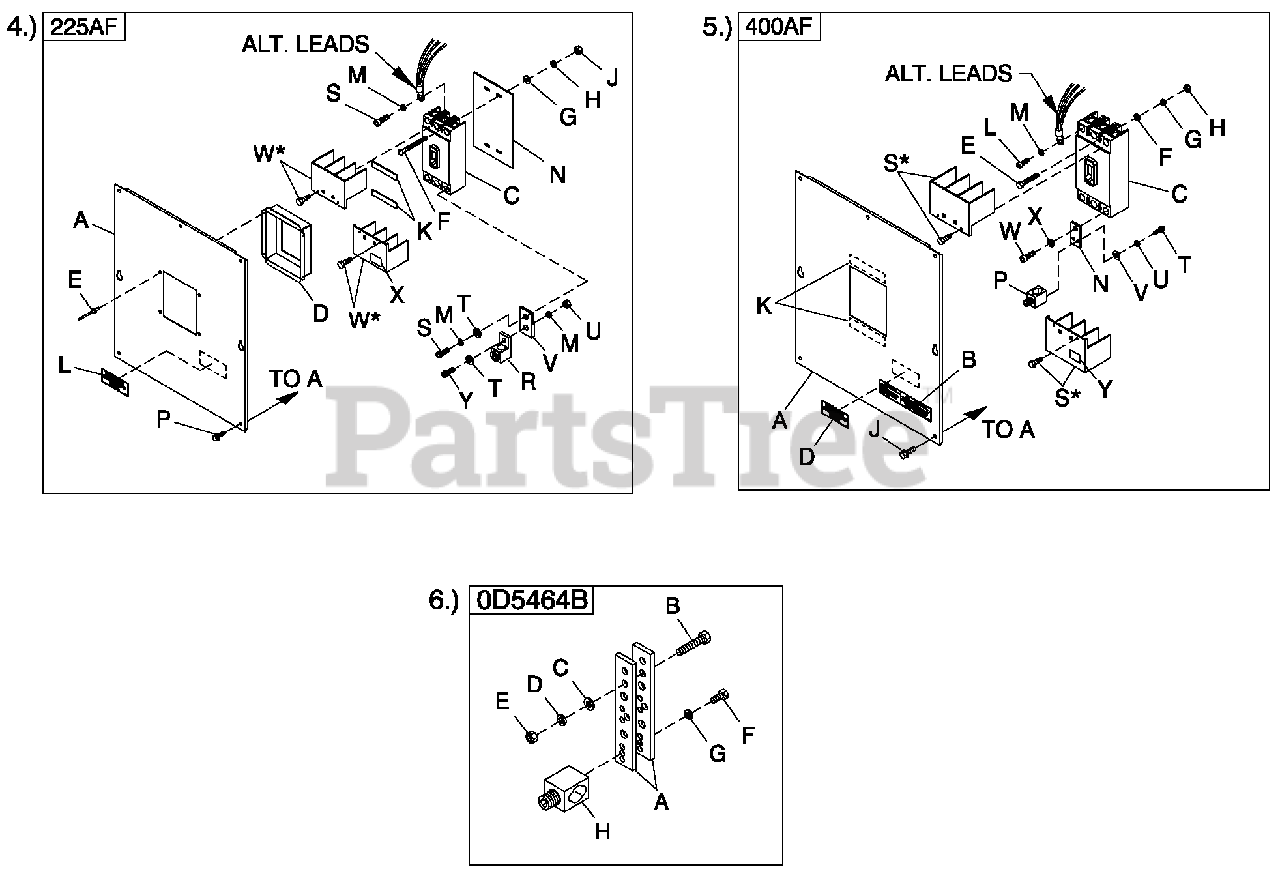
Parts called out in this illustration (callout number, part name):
A	COVER CB C3 225AF
C	CIRCUIT BREAKERS 200A FRAME
D	COVER CB DISH 225AF
E	RIVET POP .125 X .275 SS
F	SCREW RHM #8-32X3-1/4
G	WASHER FLAT #8 ZINC
H	WASHER LOCK #8-M4
J	NUT HEX #8-32 STEEL
K	TAPE ELEC 1/2 FOAM
L	DECAL CUSTOMER CONNECT INSIDE
M	WASHER LOCK M8-5/16
N	INSULATOR CB 225AF
P	SCREW THF M6-1 X 16 N WA Z/JS
R	LUG SLDLSS 300 MCM-6 AL/CU
S	SCREW SHCM8-1.25X 20 G8
T	WASHER FLAT 5/16-M8 ZINC
U	NUT HEX M8-1.25 G8 CLEAR ZINC
V	BUS BAR 200A LUG ADAPTOR
W	TERMINAL COVER CB
X	DECAL TERMINAL SHOCK HZD BI
Y	SCREW SHC M8-1.25 X 25 G12.9
A	COVER CB C3 400AF
C	CIRCUIT BREAKERS 400A FRAME
D	DECAL CUSTOMER CONNECT INSIDE
E	SCREW RHM 10-32X4
F	WASHER FLAT #10 ZINC
G	WASHER LOCK #10
H	NUT HEX #10-32 STEEL
J	SCREW THF M6-1 X 16 N WA Z/JS
L	SCREW SHC M10-1.5 X 25 G12.9
M	WASHER LOCK M10
N	BUS BAR CB ADAPTER 225-400 A
P	LUG SLDLSS 600/250-1/0 X 1/4-28
S	TERM COVER CB
T	SCREW HHC 1/4-28X1/2 G5
U	WASHER LOCK M6-1/4
V	WASHER FLAT 1/4-M6 ZINC
W	SCREW SHC M10-1.5 x 25 G12.9
X	WASHER LOCK M10
Y	DECAL TERMINAL SHOCK HZD BI
A	BUS BAR NEUTRAL BLOCK 390
B	SCREW HHC M8-1.25 X 45 G8.8 FT
C	WASHER FLAT 5/16-M8 ZINC
D	WASHER LOCK M8-5/16
E	NUT HEX M8-1.25 G8 YEL CHR
F	SCREW HHC 1/4-28 X 3/4 G5
G	WASHER LOCK M6-1/4
H	LUG SLDLSS 600/250-1/0X1/4-28
